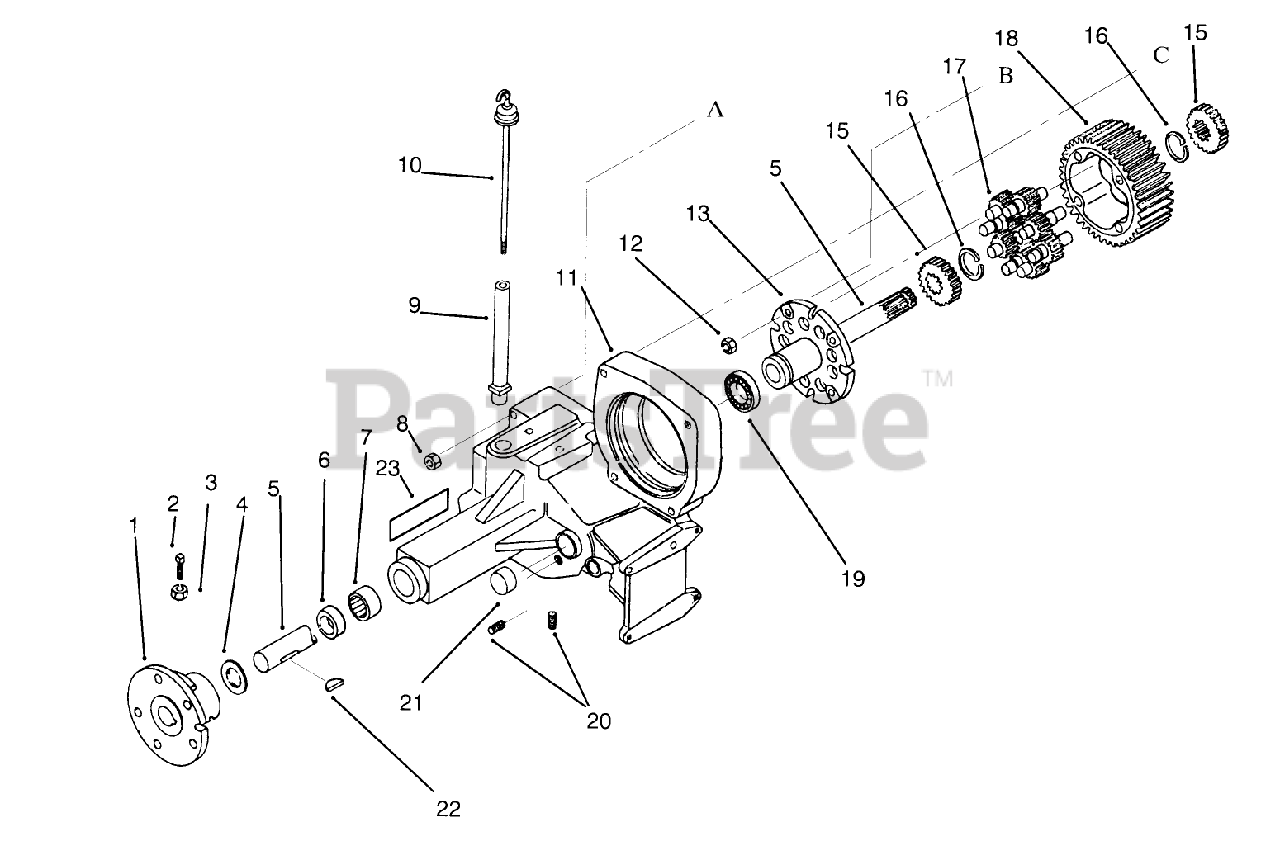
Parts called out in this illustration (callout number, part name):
2	SCREW-SET, SQH
3	NUT-JAM
4	WASHER-THRUST
6	SEAL-OIL
7	BEARING
8	NUT-LOCK, NI
9	NIPPLE-TRANS FILL
11	CASE-TRANSMISSION RH
12	NUT-HEX
13	END CAP-DIFFERENTIAL
15	GEAR-AXLE DIFFERENTIAL
16	RING-SNAP
17	GEAR-PINION, 11T
18	GEAR-DIFFERENTIAL RING, 43T
19	BEARING-BALL
21	BEARING-NEEDLE
22	KEY-WOODRUFF
23	DECAL - DANGER
